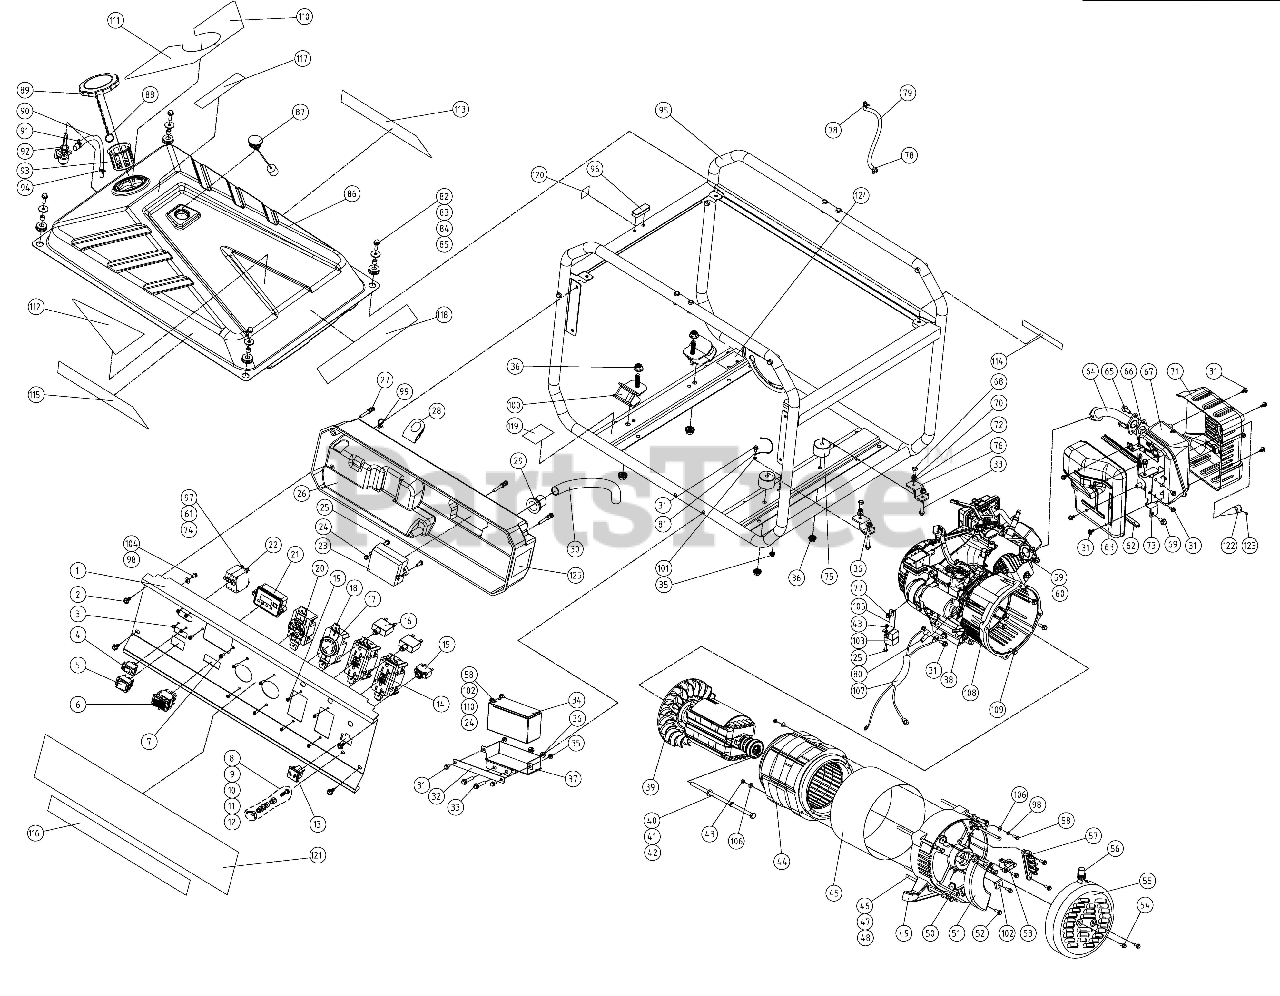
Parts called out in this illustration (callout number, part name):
1	Panel (PRO3.7)
2	SCREW, BOLT GB5789-M6X12
3	SCREW, M3X6
7	SCREW M4X12
9	SCREW, BOLT M6X25
11	WASHER, PLATE GASKET 6
12	WASHER, SPRING GASKET 6
13	RECEPTACLE, DC SOCKET 12V8.3A
14	RECEPTACLE, GFCI 20A/125V NEMA 5-20OR
15	BREAKER, CIRCUIT 10A
16	BREAKER, CIRCUIT 20A
17	RECEPTACLE, NEMA L5-30R SOCKET
18	PLATE NUT
20	RECEPTACLE, NEMA L14-30R 4P SOCKET
21	DIGITAL DISPLAY METER
22	CIRCUIT BREAKER
23	MODULD, IDLE CONTROL
25	SCREW M5X16-GB818
26	BOX, PANEL
27	SCREW M5X45
28	WIRE SHEATH
29	GROMMET, POWER CORD SHEATH
30	PIPE, CORRUGATED
31	SCREW, BOLT M6X12
32	HOLDER, BATTERY CLAMP
33	BOLT M8X40 GB 5789
34	BATTERY 12V7.5AH
37	BRACKET, BATTERY
39	ROTOR ASSEMBLY
40	BOLT 5/16-24X231 MM
42	WASHER, SPRING
44	STATOR ASSEMBLY (PRO3.7E)
45	STATOR PROTECTOR
46	WASHER, SPECIAL SPRING 6
47	WASHER, PLATE GASKET 6
48	SCREW BOLT M6X180
49	CAP, BACK COVER
50	BOLT M5X715
51	RECTIFIER AVR (PRO5.5E)
52	SCREW, BOLT GB 5787-M5X16
53	BRUSH, CARBON ASSEMBLY
54	SCREW, BOLT M5X10
55	FAN COVER
56	SLEEVE, MOTOR RUBBER SHEATH
57	BOARD ASSEMBLY, PATCH
58	BOLT GB/T 5783-M5X10
61	WASHER, SPRING GB93-4
62	RUBBER GASKET
63	MUFFLER BACK COVER
64	MUFFLER PIPE WELDING ASSEMBLY
65	SCREW, BOLT M8X22
67	MUFFLER WELDING ASSEMBLY
68	BOLT M8X16
69	SCREW, BOLT M8X16
70	WASHER, SPRING 8
71	MUFFLER FRONT COVER
72	WASHER, FLAT GASKET 8
73	MUFFLER BRACKET PRO 3.7
75	RUBBER FOOT
76	ADAPTER BRACKET
77	BOLT M6X8
78	CLAMP, FUEL PIPE 5
79	FUEL LINE
80	RUBBER CAP
81	GROUND WIRE
82	SCREW, BOLT GB 5787-M6X20
83	MOUNT, FLAT GASKET GB/T 5287-6
84	SPACER, INNER RING
85	SPACER, FUEL TANK BUSHING
86	TANK ASSEMBLY (PRO3.7E)
87	FUEL LEVEL GAUGE ASSEMBLY
88	RETAINER, TANK CAP PULL RING
89	CAP ASSEMBLY - FUEL TANK (EPA)
90	FUEL LINE
91	CLAMP, FUEL LINE 6
92	VALVE,FUEL SHUT OFF
93	FILTER , FUEL TANK
94	CLAMP, FUEL LINE 1 USE 14 237 01-S
95	FRAME ASSEMBLY
96	DAMPER, HANDLE DAMPING PAD
97	SCREW GB818-M4X8
98	WASHER, SPRING GB 93-5
99	STRAP, CABLE TIES 3.2X120 (WHITE)
100	VIBRATION ABSORBER
101	GROOVED METAL GASKET 6
102	RETAINER, 12V DC CHARGE BRIDGE
103	RECTIFIER, BLOCK (PRO5.2E)
104	SCREW M5X12
105	BRACKET, STATIONARY BARRIER
106	WASHER, PLATE GT/T 95
107	BATTERY WIRING
108	FRONT COVER
109	BOLT 5/16-24 27MM
110	LOGO LABEL (RESERVOIR PORT)
111	WARNING LABEL (FUEL TANK RIGHT)
112	RUNNING WATTS LABEL (FUEL TANK)
113	LOGO LABEL (FUEL TANK LEFT)
114	SAFETY DECAL
115	CPSC DECAL_5.2
116	QUICK START LABEL
117	DECAL, OSHA
118	DECAL, GENERATOR_WARNING
119	DECAL, SERIAL NUMBERS
120	FUEL SWITCH DECAL
121	PANEL LABEL
122	SPARK ARRESTER
124	EMC DECAL
125	(CSA) EMC DECAL
